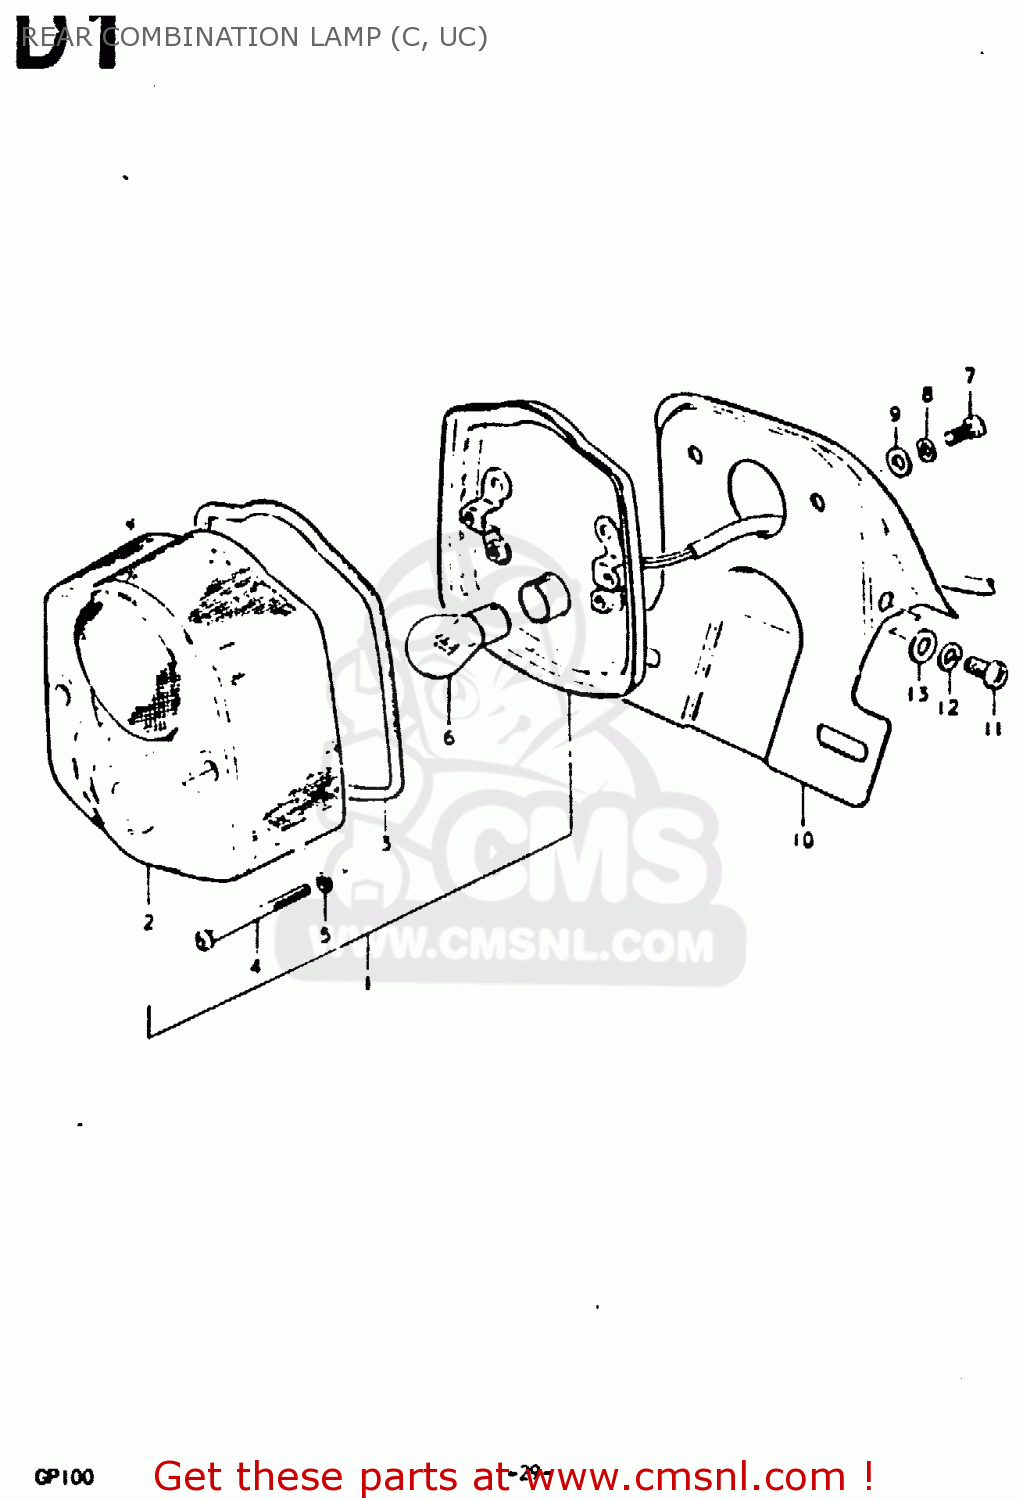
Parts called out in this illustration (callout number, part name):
1	LAMP ASSY, REAR COMBINATION
2	LENS
3	GASKET (NAS)
4	SCREW
5	GASKET (NAS)
6	BULB(6V10/3W,STANLEY,A4854H)
7	BOLT
8	LOCK WASHER
9	WASHER
10	BRACKET
11	SCREW
12	LOCK WASHER
13	WASHER
